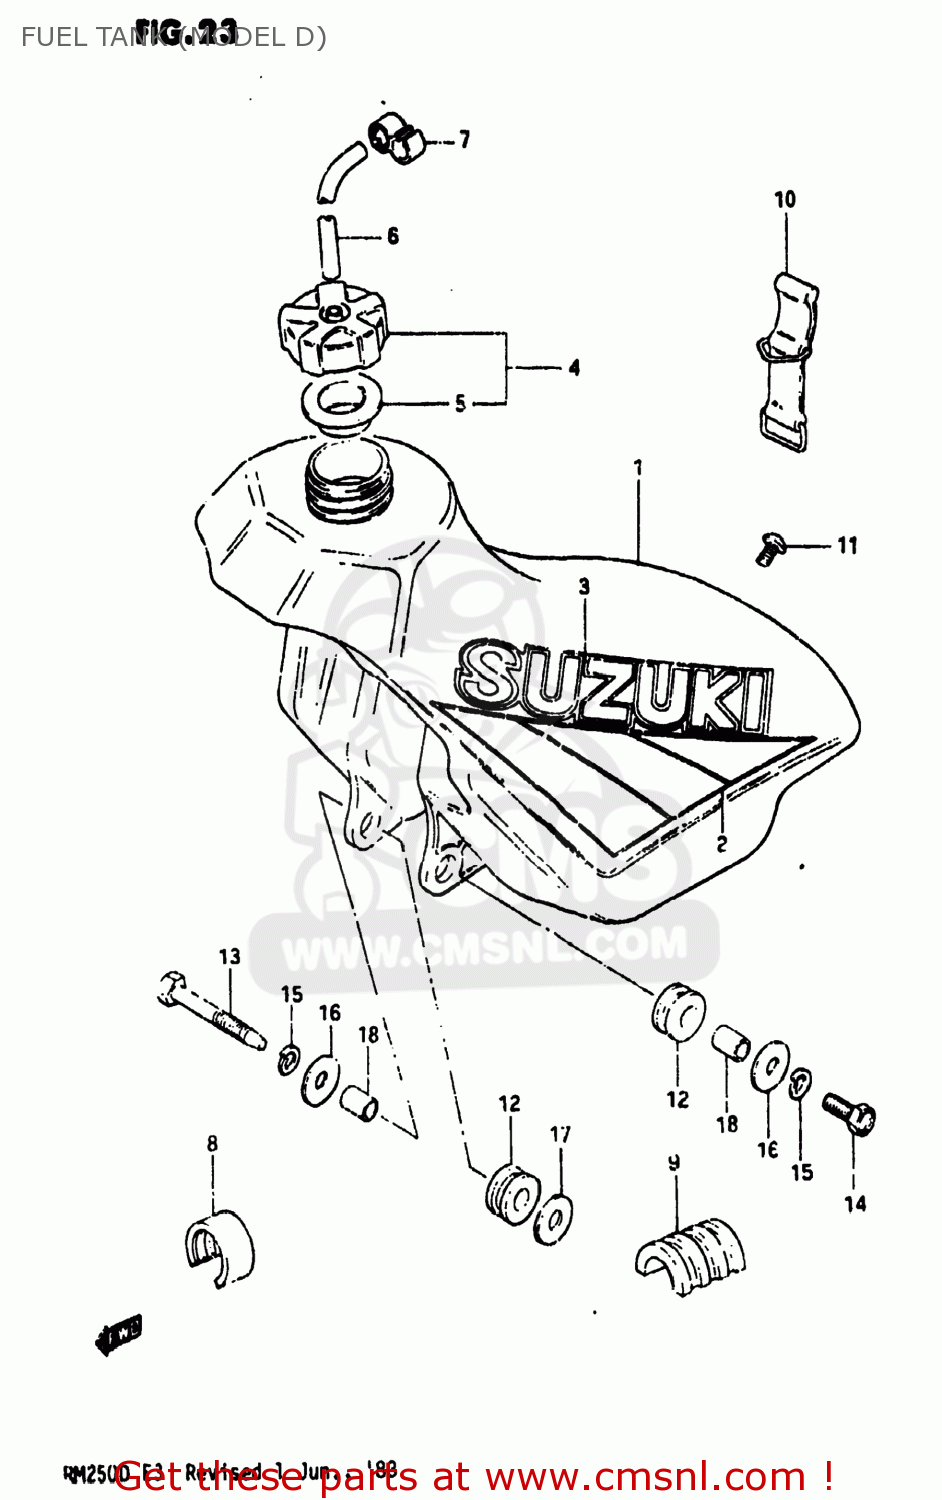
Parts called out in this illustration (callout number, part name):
1	TANK ASSEMBLY,FUEL
2	TAPE SET,FUEL TANK
3	EMBLEM
4	CAP SET,FUEL TANK
5	GASKET,FUEL TANK CAP (NAS)
6	HOSE
7	CLAMP,BREATHER HOSE
8	CUSHION,FUEL TANK UPR FR
9	CUSHION,FUEL TANK,UPPER
10	BAND
11	SCREW (6X15)
12	CUSHION
13	BOLT 8X75
14	BOLT
15	LOCK WASHER
16	WASHER
17	WASHER(8.5X26X1.2)
18	SPACER (8.8X12X13.5)
